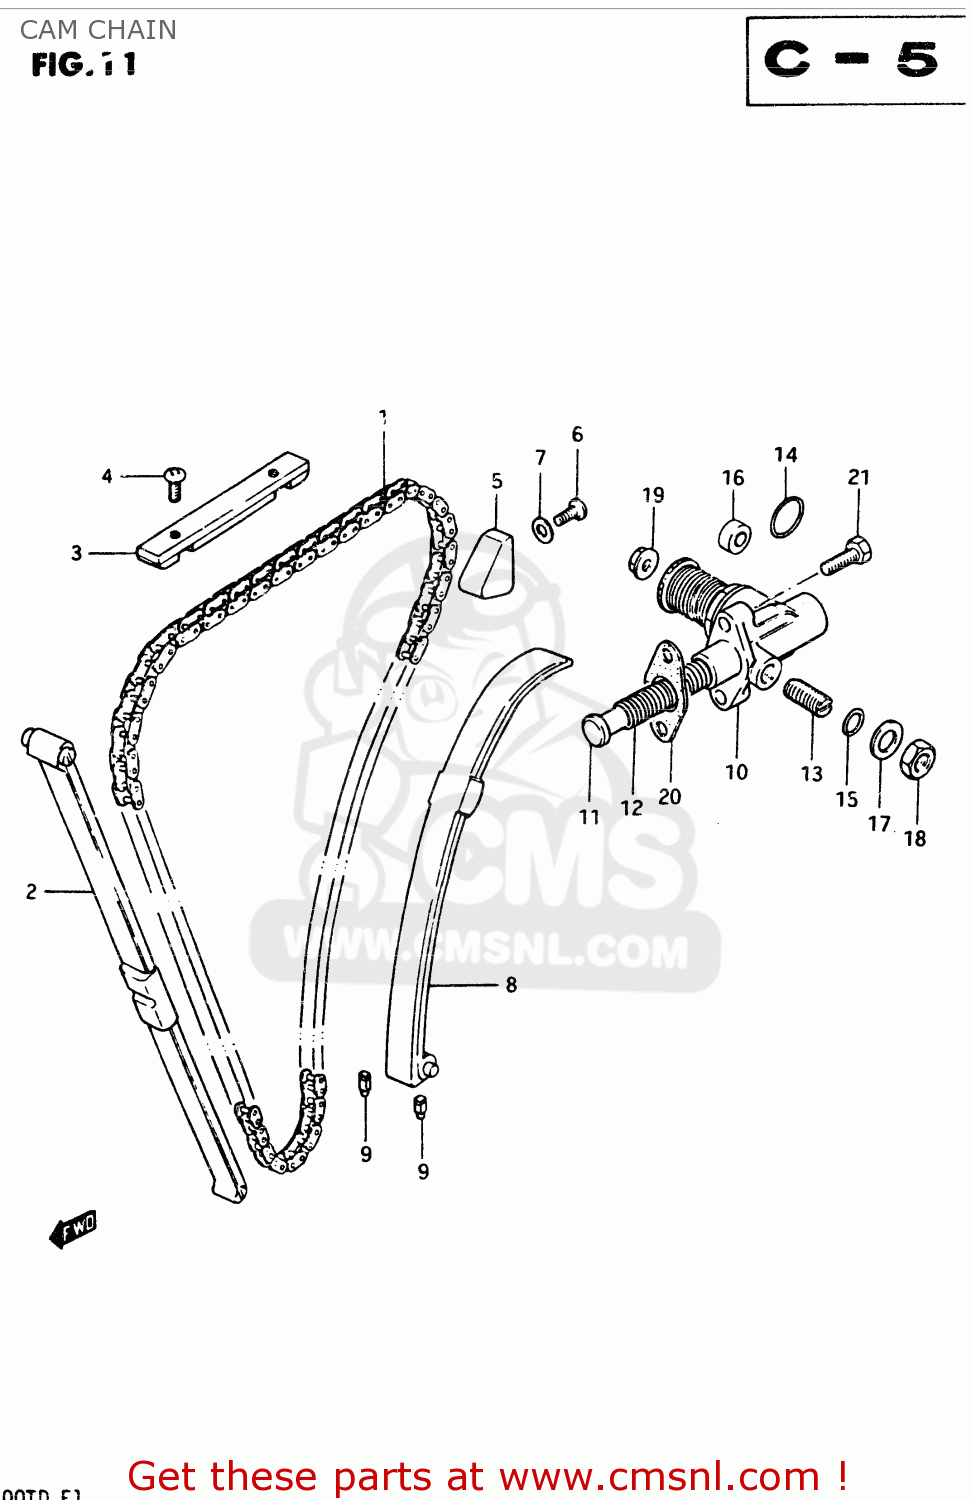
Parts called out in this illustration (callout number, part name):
1	CHAIN,CAMSHAFT DRIVE(120L)
2	GUIDE, CAM CHAIN NO.1
3	GUIDE,CAM CHAIN NO.3
4	SCREW
5	GUIDE,CAM CHAIN
6	BOLT
7	GASKET (NAS)
8	TENSIONER,CAM CHAIN
9	CUSHION,CAM CHAIN TENSIONER
10	ADJUSTER,CAM CHAIN TENSIONER
11	ROD,PUSH
12	SPRING
13	SCREW
14	O-RING
15	O-RING
16	OIL SEAL
17	WASHER
18	NUT
19	NUT
20	GASKET,TENSIONER ADJUSTER (MCA)
21	SCREW (6X25)
